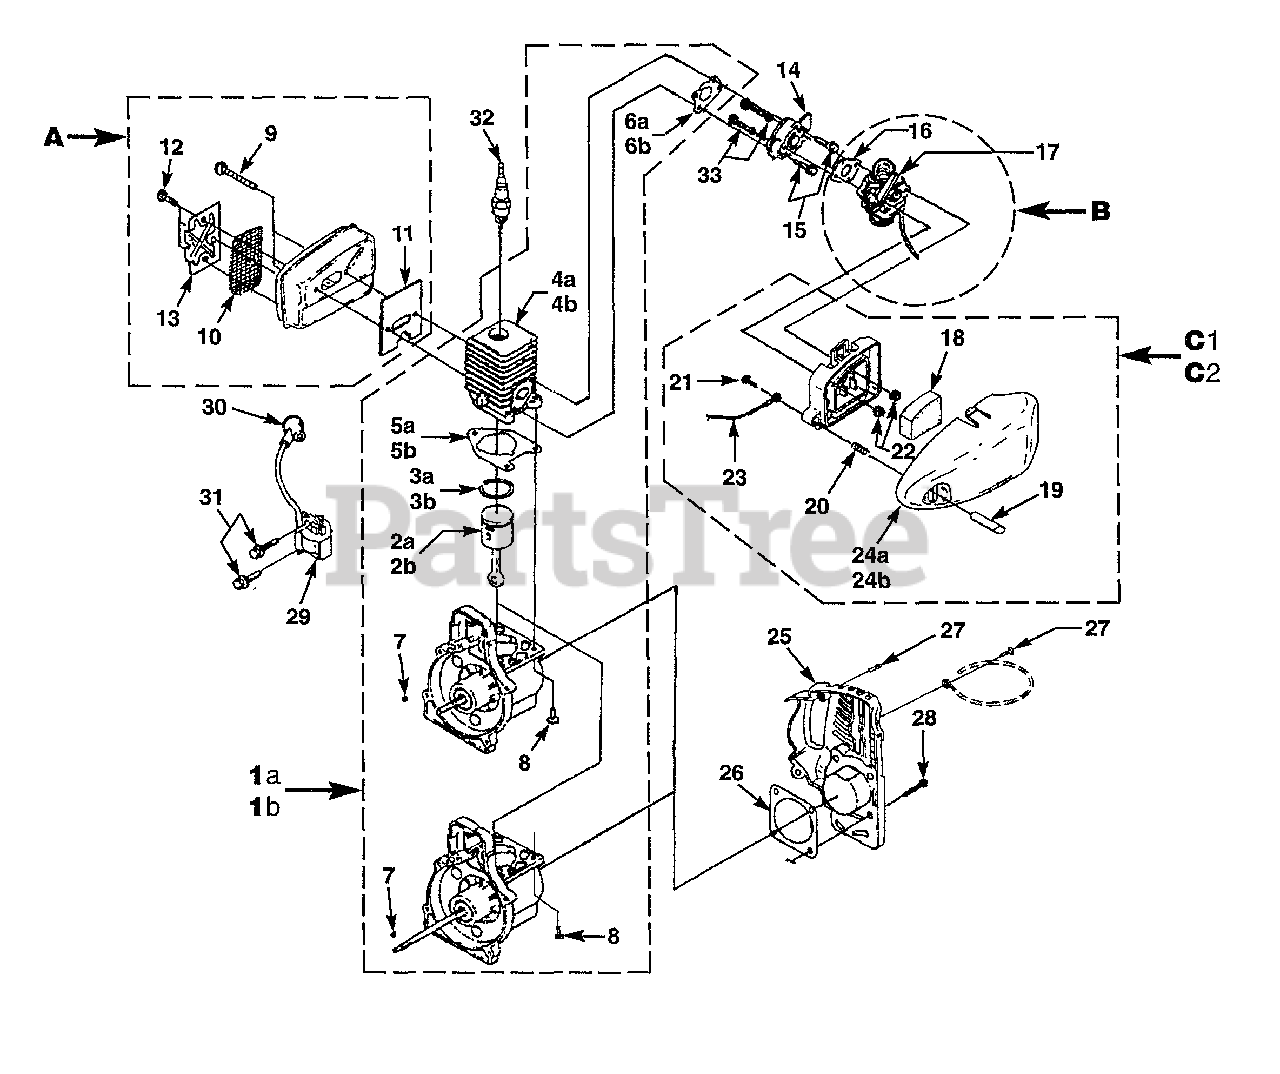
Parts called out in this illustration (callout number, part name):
1A	SHORT BLOCK (30CC Non-Clutch Models)
1B	SHORT BLOCK (30CC Clutch Models)
2A	30CC PISTON ROD
2B	25CC PISTON & ROD
3A	RING-Piston
3B	RING-Piston
4A	30CC CYLINDER KIT
4B	25CC CYLINDER KIT
5A	GASKET-Cylinder
5B	GASKET-Cylinder
6A	GASKET-Heat Dam
6B	GASKET-Heat Dam
7	KEY-Woodruff
8	SCREW-Thread Form. (10-24 X 3/4")
9	SCREW-Machine (#10-24 X 2")
10	SCREEN-Spark
11	GASKET-Muffler
12	SCREW-Machine-Pan Slotted (8-32 X 3/4")
14	HEAT DAM
15	SCREW-Taptite (10-24 X 1")
16	GASKET-Carburetor
17	LEVER-Choke Rod-(ZAMA)
18	FILTER-Air
19	BUTTON-Switch
20	SPRING-Compression
21	SCREW-Plastite (#6-19 X 1/2")
22	NUT-HEX (10-24)
22	NUT-Hex (10-24)
23	LEAD-Electrical
24A	COVER-Air Filter
24B	COVER-Air Filter
25	CRANKCASE COVER
26	GASKET-Crankcase Cover
27	SCREW-Plastite (#10 X 3/4")
28	SCREW-Taptite(10-24 X 5")
29	MODULE-Ignition
30	TERMINAL & COVER
31	SCREW-Taptite (8-32 X 1")
32	SPARK PLUG
33	SCREW-Machine (50-24 X 2 1/4")
A	MUFFLER KIT
B	CARBURETOR
C1	AIR FILTER KIT W/PUSH-BUTTON STOP
C2	AIR FILTER KIT W/O PUSH-BUTTON STOP
